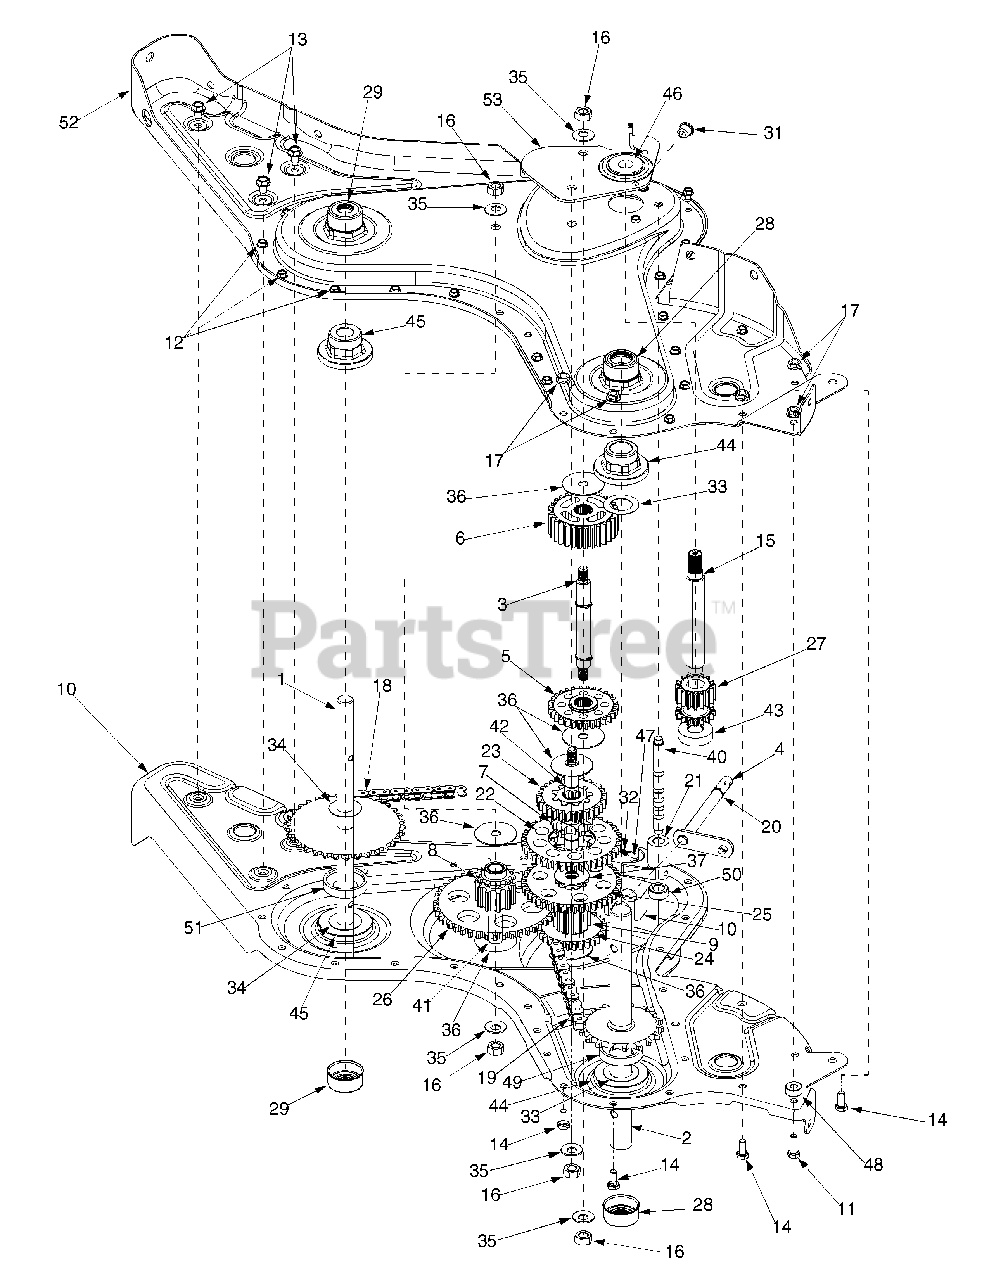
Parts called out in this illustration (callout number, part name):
1	Wheel Shaft Assembly 33T
2	Tine Shaft Assembly: 18T
3	Jack Shaft Assembly
4	Input Shaft
5	Rev. Idler Gear Assembly: 30T
6	Tine Idler Gear Assembly: 30T
7	Tine Input Sprocket Assembly: 9T
8	Wheel Input Sprocket Assembly: 10T
9	Gear Assembly: 11T
10	R.H. Housing Assembly
11	Hex Bolt 5/16-18 x 1" Lg.
12	Hex S-Tap Scr. 1/4- 20 x.5"
13	Hex S-Tap Scr. 5/16-18 x. 625"
14	Hex Bolt 5/16-18 x.75"
15	Input Shaft
16	Hex Nut 7/16-20
17	Flange Nut 5/16-18
18	#420 Chain 1/2 Pitch x 50 Links
19	#50 Chain 5/8 Pitch x 54 Links
20	Snap Ring
21	Shifting Fork
22	Spur Gear 44T
23	Spur Gear 30T
24	Spur Gear 30T
25	Spur Gear 44T
26	Spur Gear 44T
27	Spur Gear 16T
28	Seal 1.0 Shaft
29	Seal.75 Shaft
31	Taper Cap Ring
32	Compression Spring.50" Leg.
33	Thrust Wash. 1.03" I.D. X. 1.62"
34	Fl-Wash.76" I.D. x 1.5" O.D
35	Bell-Wash .45" I.D. x 1.0"
36	Thrust Wash. .445 x 1.92 x .060
37	Fl-Wash. .635" I.D. x 1.59 OD
40	Detent Shaft 1/2" Dia.
41	Jack Shaft .625 x 2.385
42	Jack Shaft .625 x 5.0
43	Ball Bearing
44	Flange Bearing 1.0 x 2.5 x 1.38
45	Flange Bearing .75 x 2.5 x 1.38
46	Ball Bearing . 6692 x 5745 x .466
47	Detent Ball .250
48	Spacer .315
49	Spacer 1.0 I.D x 2.0 O.D
50	Spacer .505 I.D. x .88 O
51	Spacer .75 x 2.0 x .50
52	L.H. Chain Case Assembly
53	Gear Positioner Bracket
